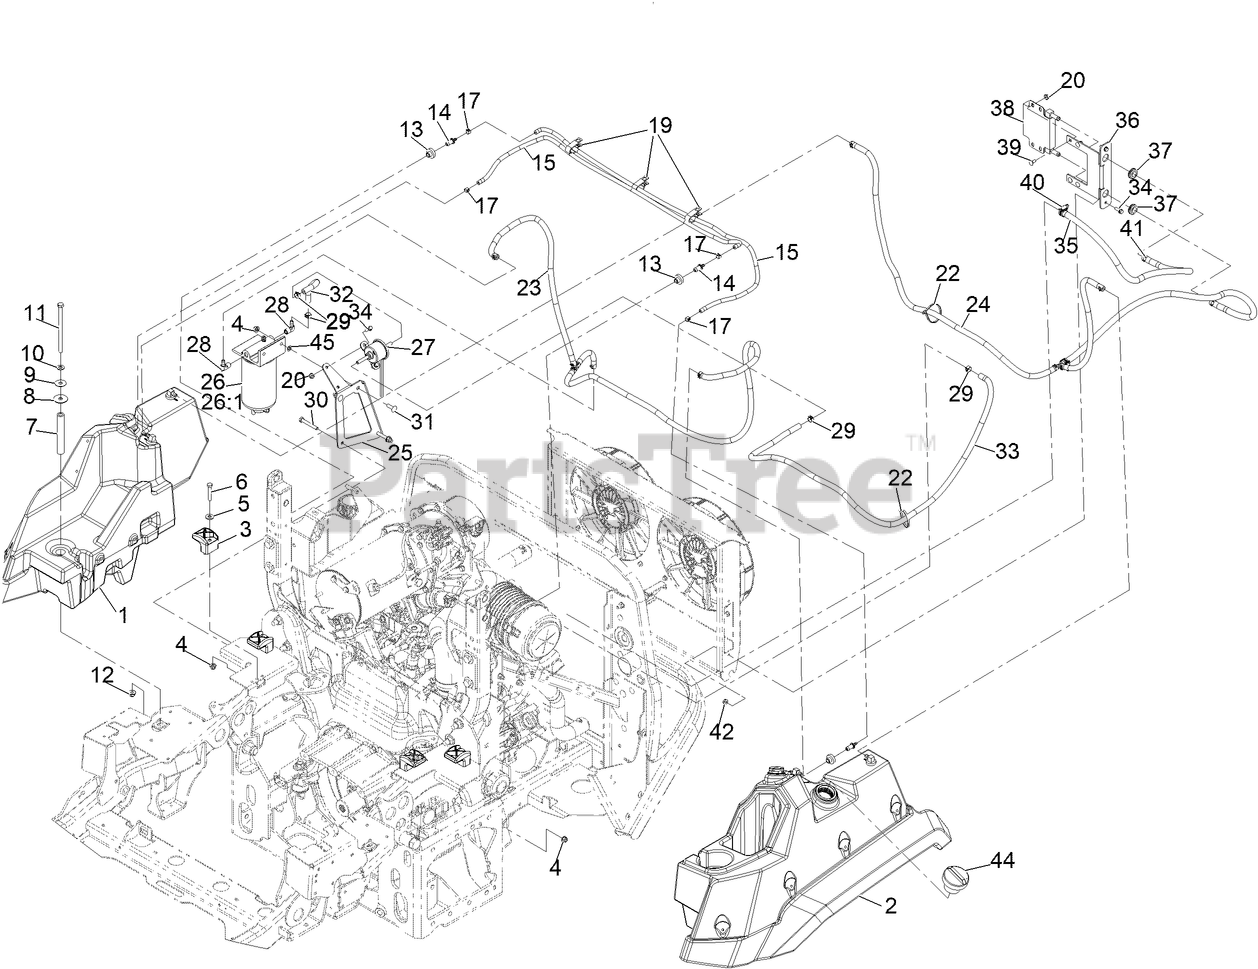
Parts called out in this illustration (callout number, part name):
1	RH FUEL TANK ASM
2	ASM-FUEL TANK, LH
4	NUT-HF, NI
5	WASHER-FLAT
6	SCREW-HH
7	TUBE-SPACER
8	WASHER-RUBBER
9	WASHER-PLAIN
10	WASHER-FLAT
11	SCREW-HH
12	NUT-HF, NI
13	BUSHING
14	FITTING-ORIFICE, STRAIGHT
15	HOSE-VENT, TANK
17	CLAMP-HOSE
19	CLAMP-HOSE
22	TIE-CABLE
23	FUEL SUCTION LINE ASM
24	HOSE ASM-FUEL, TEE
25	BRKT-FUEL FILTER
26	FILTER-WATER/FUEL SEPERATOR
26:1	FILTER-FUEL/WATER SEP.
27	PUMP-FUEL, ELECTRIC
28	FITTING-HYD, 90
29	CLAMP-HOSE
30	SCREW-HH
31	SCREW-CARR
32	HOSE-FUEL
33	HOSE-FUEL
34	SCREW-HWH
35	HOSE-FUEL
36	MOUNT-COOLER, FUEL
37	GROMMET
38	COOLER-OIL
39	SCREW-CARR
40	Clamp-Hose
41	CLAMP-HOSE
44	CAP-FUEL, DIESEL ULTRA LOW SULFUR
45	RING-RETAINING, BOLT
